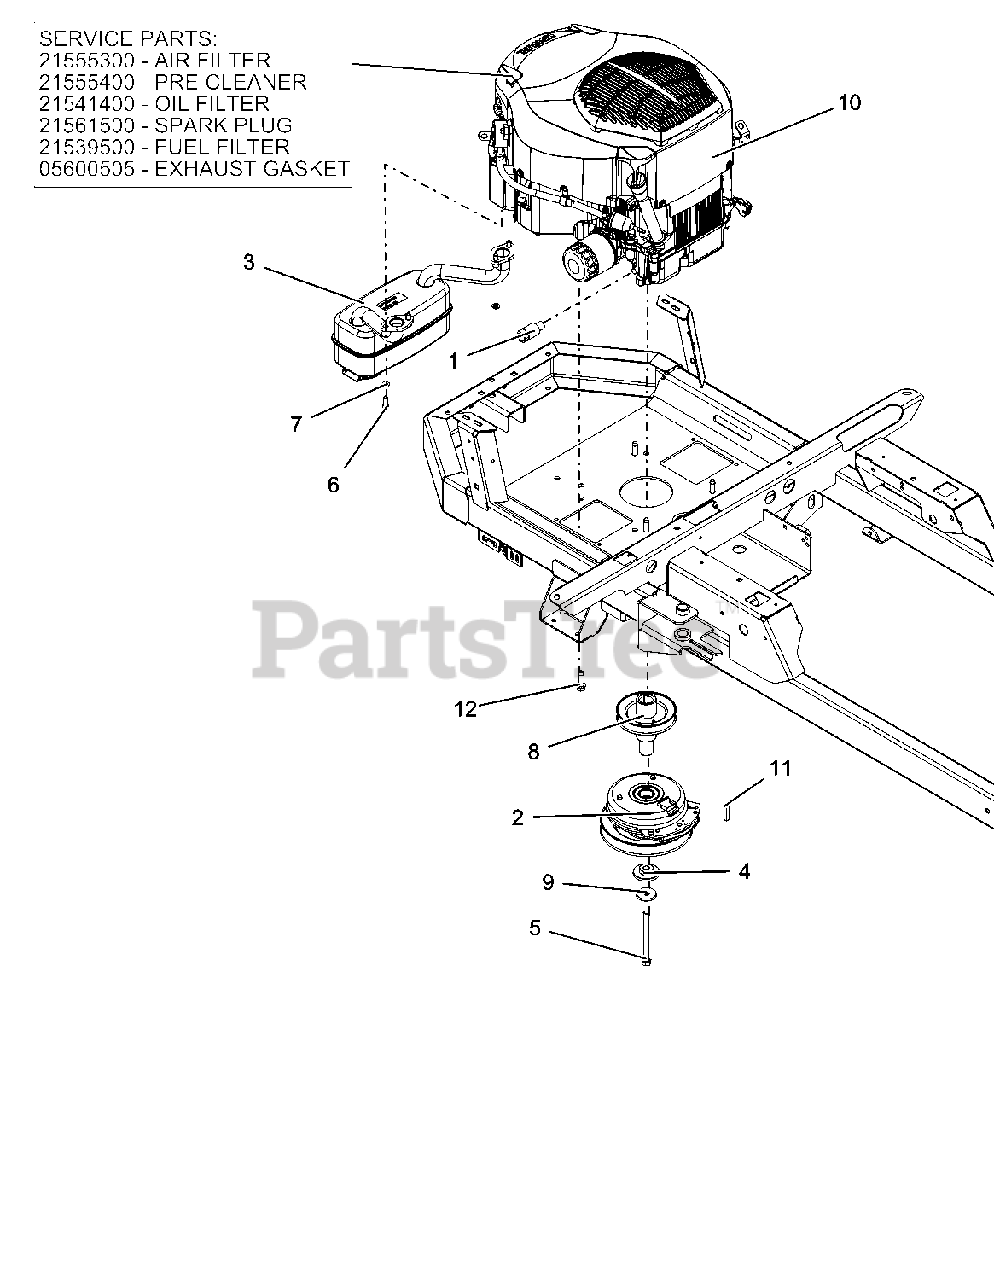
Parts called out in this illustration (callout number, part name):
1	DRAIN, OIL
2	CLUTCH, ELEC 105 FT LB MONOPOLE 6.83"
3	MUFFLER, KOHLER
4	BSHG, -FLG .469 x 1.06 x .574 x 2.0
5	BLT-HEX .44-20X4.50 GR8 YWZC NYTORQ
6	SCR, CAP SOCKET HEAD
7	WSHR-LK .31X.078 REG YWZC
8	WLDMT, DRIVE SHEAVE X (2016)
9	WSHR, 7/16" SPRING DISC
10	ENGINE, KOHLER PRO24 W/SC
10	AIR FILTER
10	PRE CLEANER
10	OIL FILTER
10	SPARK PLUG
10	FUEL FILTER
10	EXHAUST GASKET
11	KEY-SQ .250X.250X1.250
12	SCR-TAP .38-16X1.25 HWH TR YZ
